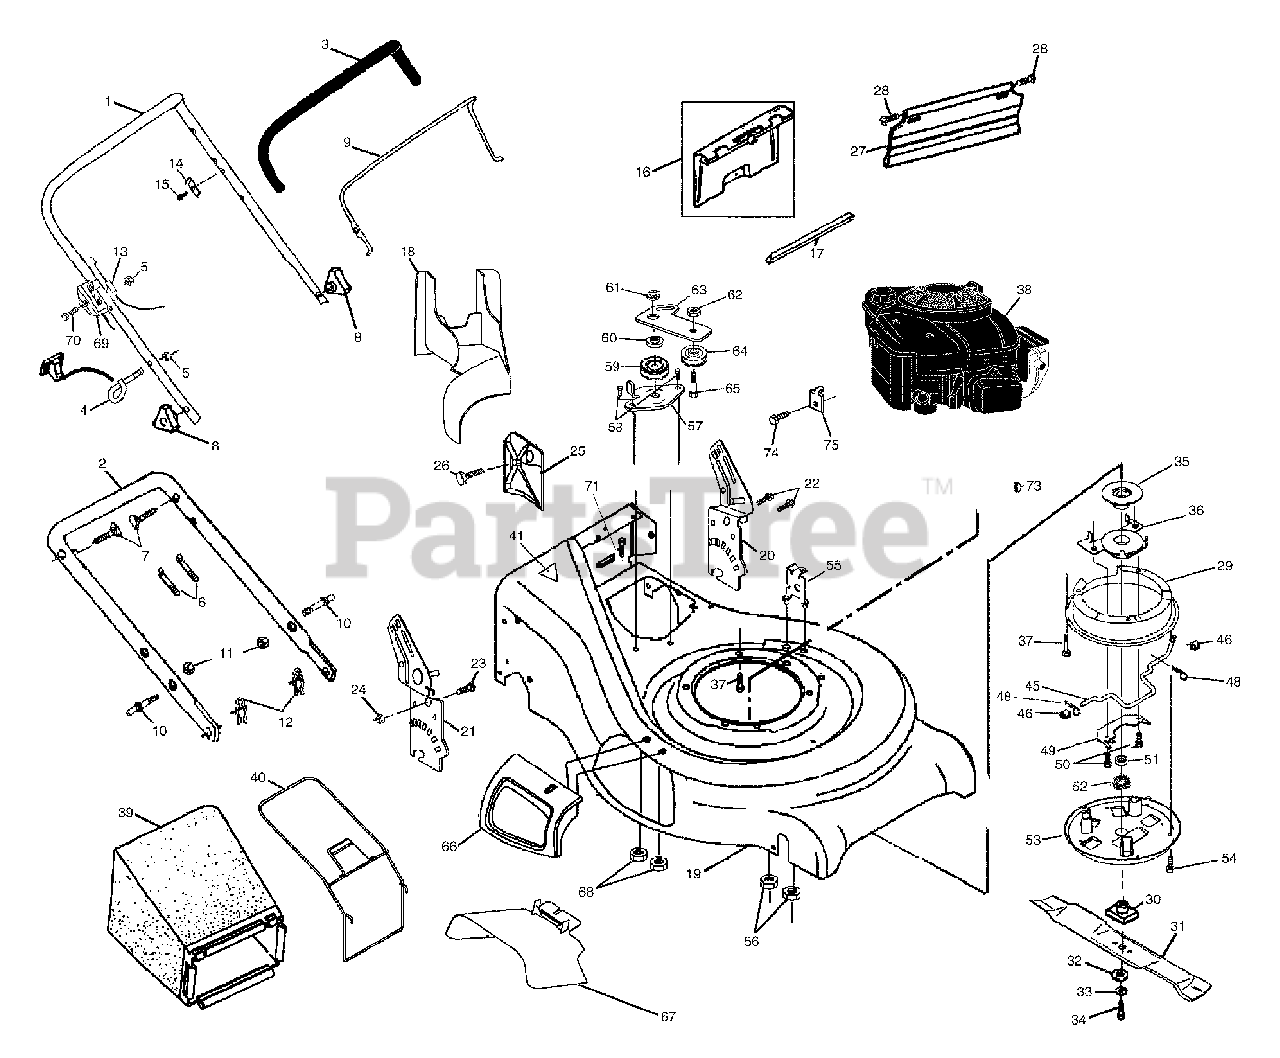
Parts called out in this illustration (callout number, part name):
1	Handle, Upper Dlx Comf.
2	Handle,Lower
3	Grip, Hdl Foam Smooth
4	Guide, Rope, Side
5	Nut, Hex Lockwasher 1/4-20
6	Wire, Tie
7	Bolt, Handle 5/16-18 x 1.75
8	Knob, Handle
9	Bail, Cont. Wire Dlx Comf. Yel
10	Bolt, Sq. Neck
11	Nut, Hex Lockwasher Ins. 5/16-18 UNC
12	Cotter, Hairpin
13	Engine zone control cable
14	Bracket, Upstop
15	Screw, Hex Washer Head Tapping 10-2
16	Kit, Door Rear
17	Seal, Door
18	Plug, Mulcher
19	Kit, Housing
20	Handle, Bracket Asm. Left
21	Handle, Bracket Asm. Right
22	Screw, Hex Wshd
23	Bolt, Hex Head 5/16-18 x 5/8
24	Nut, Hex Lock Wshr 5/16-18
25	Baffle, Side
26	Screw 12 x 5/8
27	Skirt
28	Screw, Hinge 1/4-20 x 1.25
29	Belt Cover, Top
30	Adapter, Blade w/key Longer
31	Blade, 21"
32	Washer,Hardened
33	Lockwasher, Helical Spring 3/8
34	Screw, Hex Head 3/8-24 x 1.38
35	Pulley, Fixed
36	Bearing Support Assy.
37	Bolt, Engine
39	Grass Catcher Bag
40	Grass Catcher Frame
41	Danger Decal
45	Engagement Rod
48	Retainer Clip
49	Clamp
52	Wave Washer
53	Belt Cover, Bottom
54	Screw
55	Cable Support Bracket
56	Nut
57	Bracket Assy.
59	V-Groove Pulley
60	Idler Arm Spacer
61	Flange Nut
62	Locknut
63	Idler Arm
64	Idler Pulley
65	Shoulder Bolt
66	Door Assy.
67	Deflector, Door
69	Throttle Control
70	Screw
73	Hi Pro Key
75	Cable Clamp
